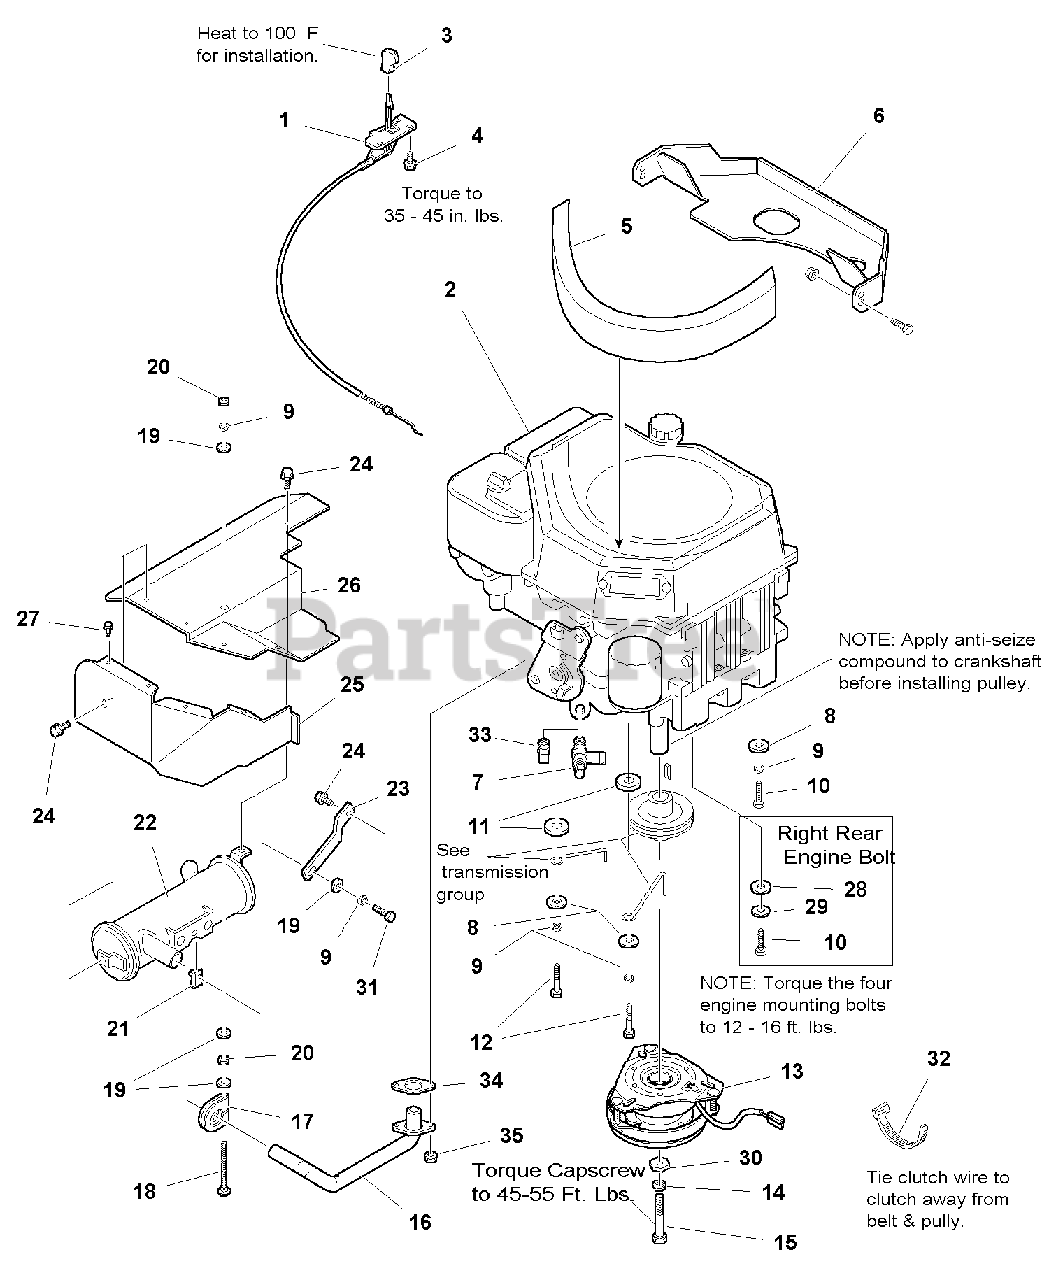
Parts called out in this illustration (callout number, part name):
1	THROTTLE CONTROL ASSEMBLY
3	KNOB, Throttle
4	CAPSCREW, Plastite, 1/4-10 x 1/2
5	SEAL, Air Inlet
7	VALVE, Shut Off
8	WASHER, Plain, 5/16
9	LOCKWASHER, 5/16
10	CAPSCREW, Hex, M08 - 1.25 x 30mm
11	WASHER, Plain
12	CAPSCREW, Hex Head, M08 - 1.25 x 40mm
13	CLUTCH, Electric
14	LOCKWASHER, 7/16
15	CAPSCREW, Hex, 7/16-20 x 3
16	PIPE, Exhaust
17	CLAMP, Muffler
18	CARRIAGE BOLT, 5/16-18 x 3-1/4
19	WASHER, 5/16
20	NUT, Hex, 5/16-18
21	NUT, Speed, 5/16-18
22	MUFFLER ASSEMBLY
23	SUPPORT, Muffler
24	CAPSCREW, Hex, Taptite, 5/16-18 x 1/2
25	AIR DUCT, Bottom
26	SHIELD, Muffler
27	CAPSCREW, Hex, Thd. Form, #10-16 x 3/8
28	WASHER, Plain, 5/16
29	LOCKWASHER, Internal Tooth, 5/16
30	WASHER, Hex
31	CAPSCREW, Hex Head, 5/16-18 x 1
32	TIE, Self Locking
33	PLUG, Fuel
34	GASKET, Muffler
35	NUT, Hex Flange
